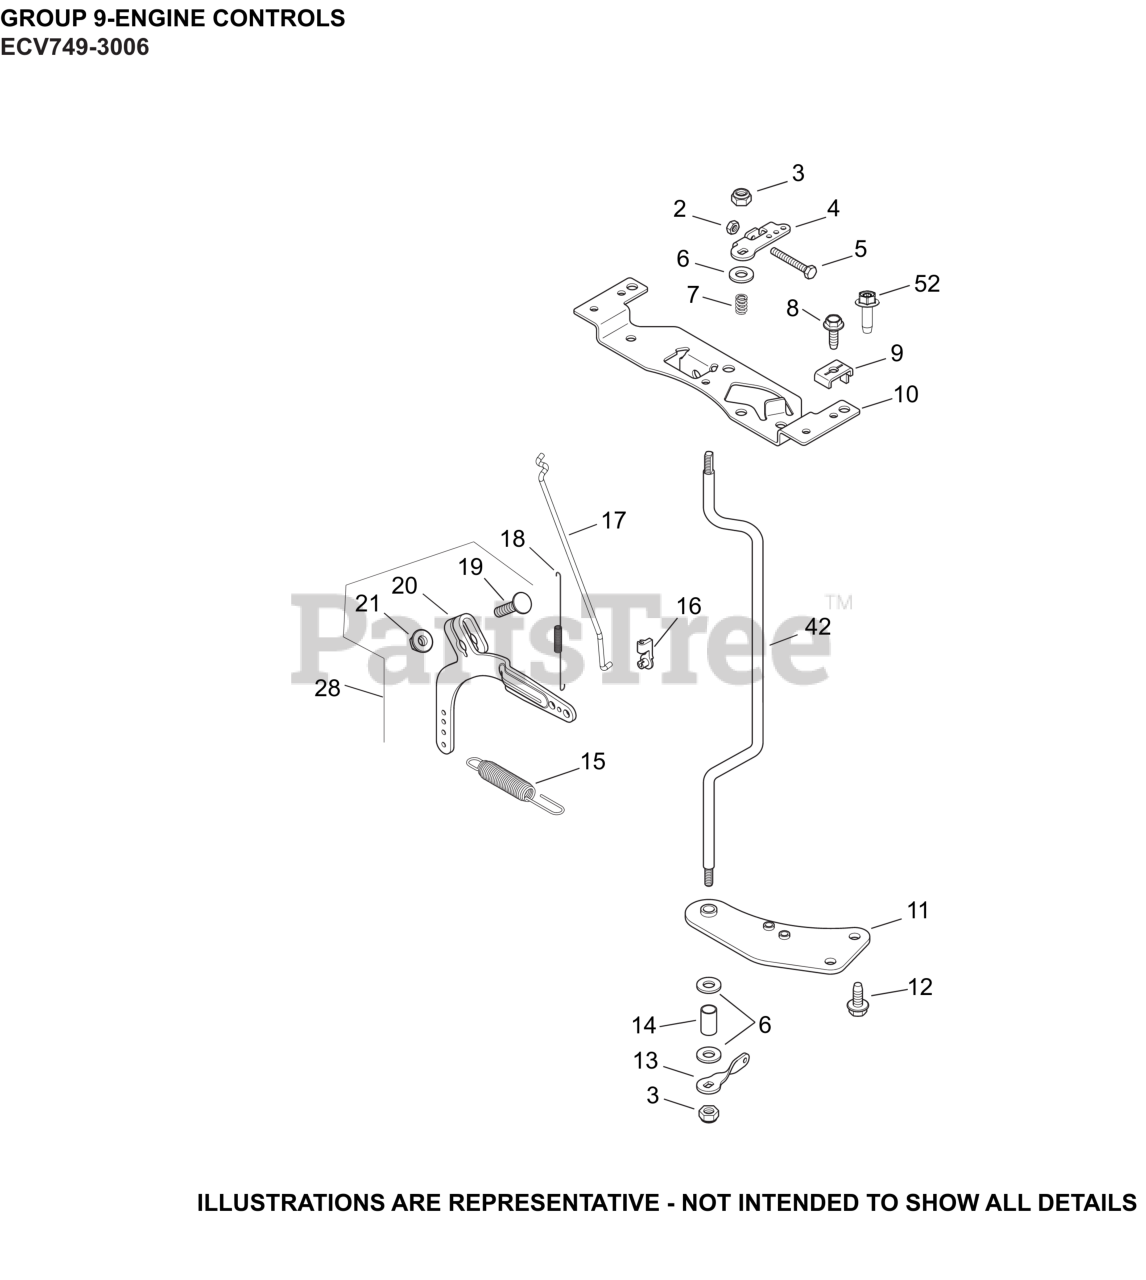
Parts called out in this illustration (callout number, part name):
2	NUT, M4X0.7
3	NUT, LOCK M6X1.0
4	LEVER, THROTTLE CONTROL
5	SCREW, CAP M4X.7X30
6	WASHER, FLAT 1/4"
7	SPRING, THROTTLE SHAFT
8	SCREW, MATHREAD M5 X 0.8 X 16
9	CLAMP, CABLE
10	BRACKET, CONTROL
11	BRACKET, THROTTLE SHAFT
12	SCREW, THREAD FORMING
13	LEVER, THROTTLE CONTROL
15	SPRING, GOVERNOR (BLACK)
16	BUSHING, THROTTLE LINKAGE
17	LINKAGE, THROTTLE
18	SPRING, LINKAGE
19	BOLT, RD HD SQ NECK M6X1.0X25
20	LEVER, GOVERNOR - (#2409069S)
21	NUT, FLG M6X1.0
28	LEVER, GOVERNOR ASSEMBLY
42	THROTTLE CONTROL SHAFT
52	SCREW, THREAD FORMING
